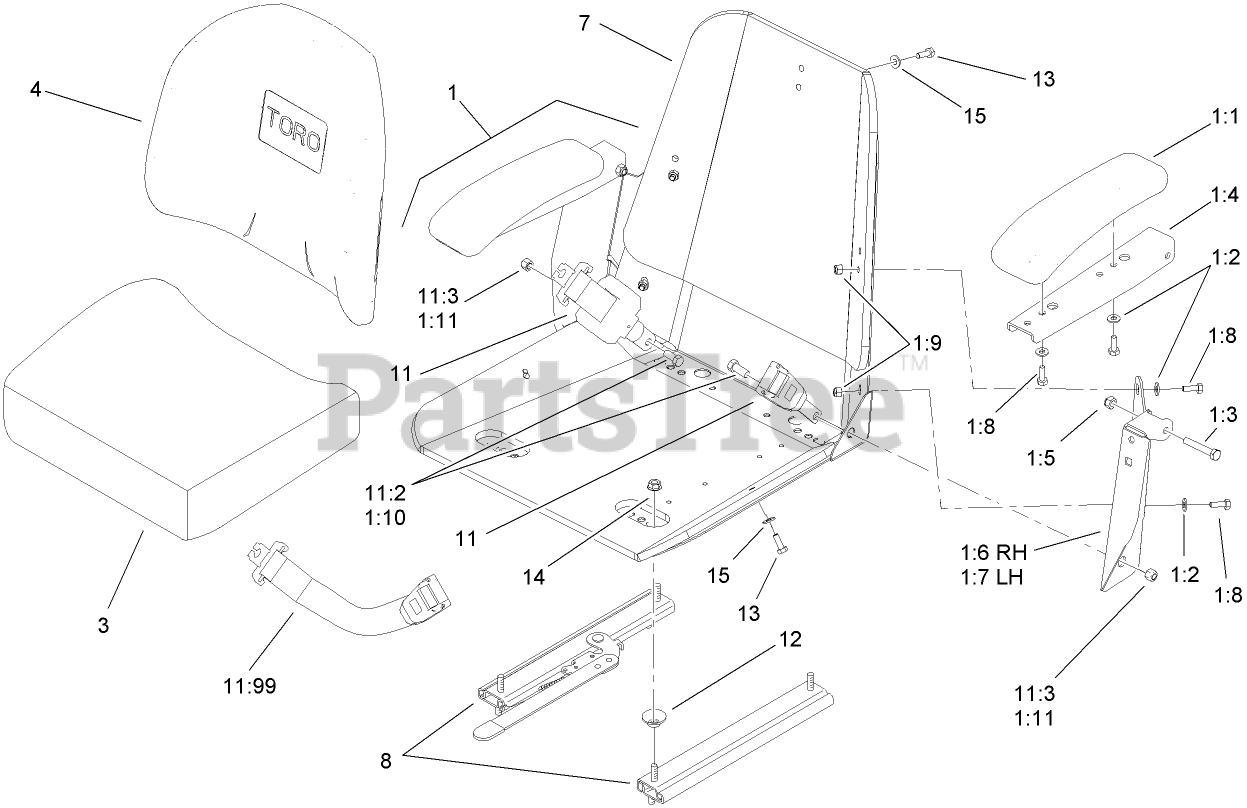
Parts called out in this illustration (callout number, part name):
1	ARMREST KIT
1:1	CUSHION-REST, ARM
1:2	WASHER-FLAT
1:3	SCREW-HH
1:4	CHANNEL-ARMREST
1:5	NUT-HEX, SIDE DEFORM
1:6	Bracket-Armrest, RH
1:7	Bracket-Armrest, LH
1:8	SCREW-HH
1:9	NUT-LOCK, NI
1:10	SCREW-HH
1:11	NUT-LOCK, NI
3	CUSHION-SEAT, BOTTOM
4	CUSION-SEAT, BACK
7	FRAME-SEAT
8	TRACK-SEAT
11	RETRACTABLE SEATBELT KIT
11:2	SCREW-HH
11:3	NUT-LOCK
11:99	SEAT BELT EXTENSION KIT
12	SPACER-TRACK
13	SCREW-HH
14	NUT-HF
15	WASHER-FLAT
